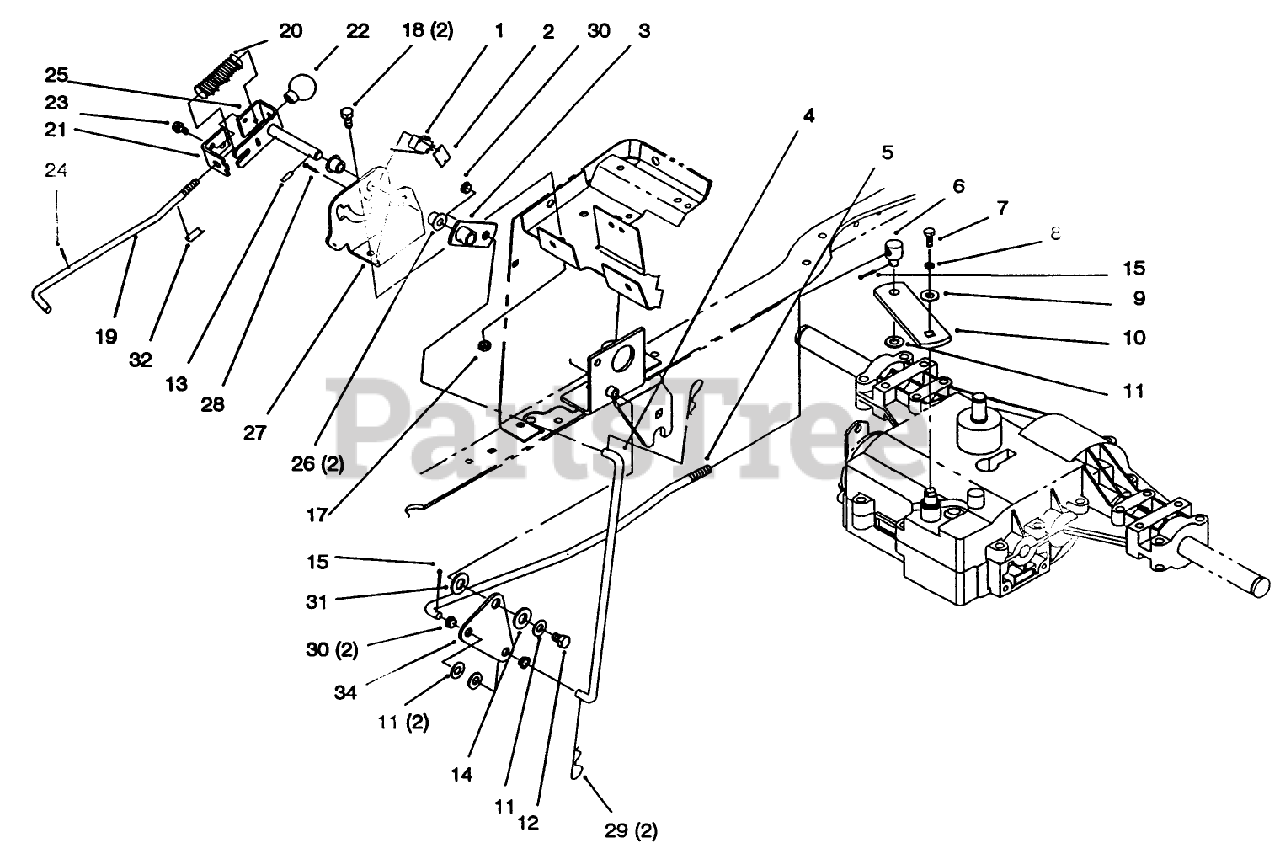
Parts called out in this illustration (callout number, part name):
1	SWITCH - CLUTCH
2	NUT-SPEED
3	TUBE-LINKAGE ASM
4	ROD - LINKAGE
5	ROD - TRANSAXLE SHIFT
7	SCREW-HH
8	WASHER-LOCK
9	SPACER
10	BRK-TRASXL SHI
11	WASHER-FLAT
12	SCREW-HH
13	PIN-ROLL, SLOTTED
14	WASHER-BELLEVILLE
15	PIN-COTTER
17	NUT-LOCK, NI
18	SCREW-HH
19	ROD - SHIFT
20	SPRING-COMPRESSION
21	BRACKET - SHAFT
23	SCREW-HWH
25	PIVOT ARM WA PLATED
26	BUSHING
27	BRKT-PIVOT MTG
31	WASHER-THRUST
32	DECAL - REVERSE GEAR
32	DECAL - REVERSE SHIFT
